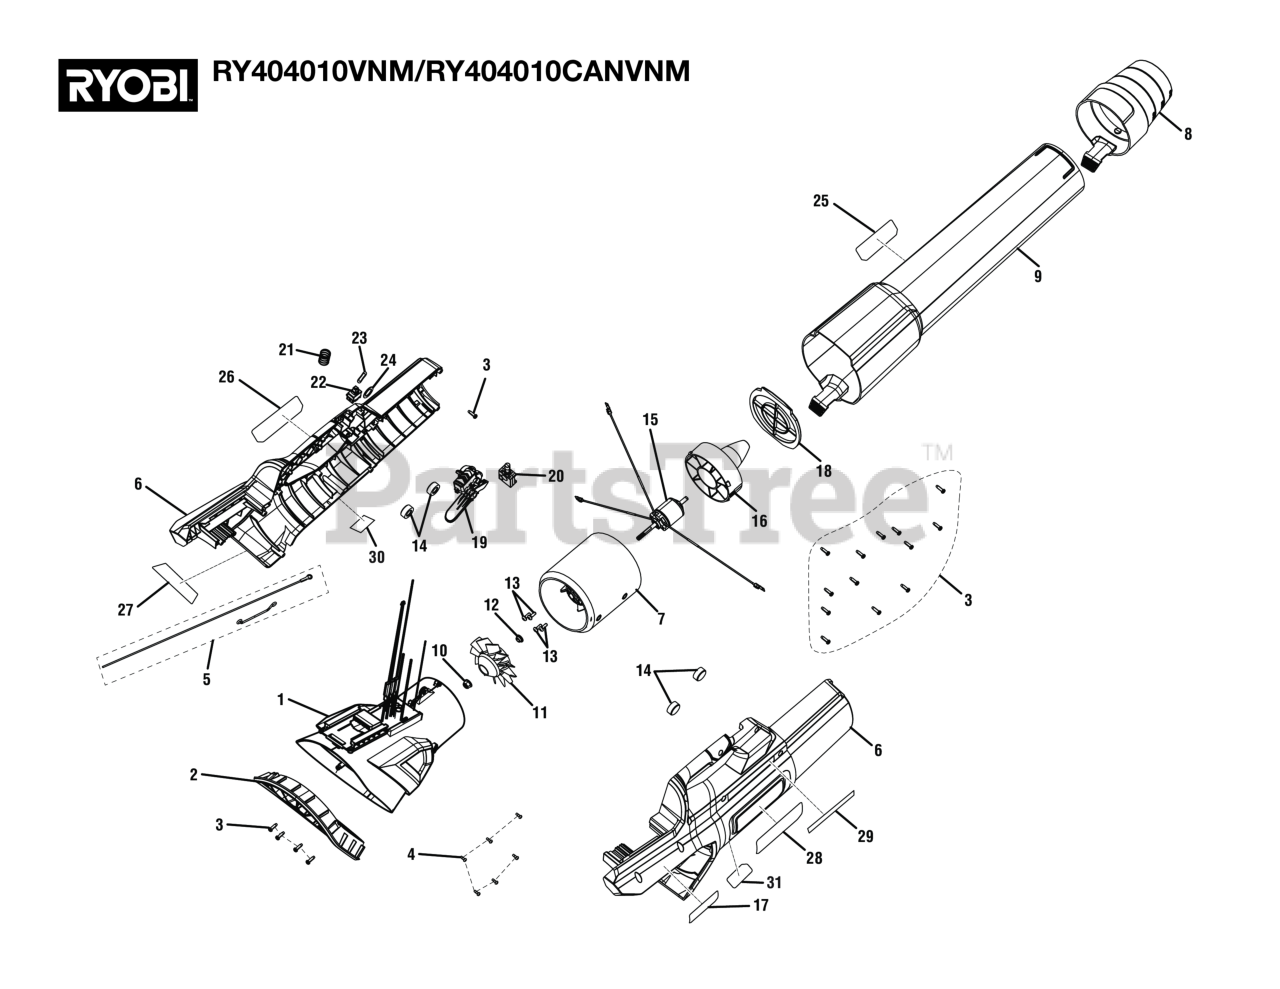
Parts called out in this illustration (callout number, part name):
1	Motor Controller and Inlet Bell Assembly
2	Inlet Guard
3	Screw (M4 x 14 mm, T15 Torx Pan Hd.))
4	Screw (M3 x 8 mm, Pan Hd., Pan Hd)
5	Grounding Strap Assembly
6	Housing Assembly (Inc. Key Nos. 17 & 26-29)
7	Stator Assembly
8	Speed Nozzle Assembly
9	Blower Tube Assembly (Inc. Key No. 25)
10	Flange Lock Nut (M6 x 1 mm)
13	Screw w/Tooth Washer (M4 x 12 mm, Pan Hd.)
14	Rubber Cap
16	Nose Cone
17	Ingestion Icon Label
18	Cross-Hairs
19	Trigger and Cruise Control Assembly
20	Signal Switch
22	Push Switch
23	Wave Washer
24	Washer (OD21 x 14 x 1t)
25	40V HP BRUSHLESS Logo Label
26	RYOBI 40V HP Logo Label
27	WHISPER SERIES Logo Label
28	Data/Warning Label
29	Icon Label
